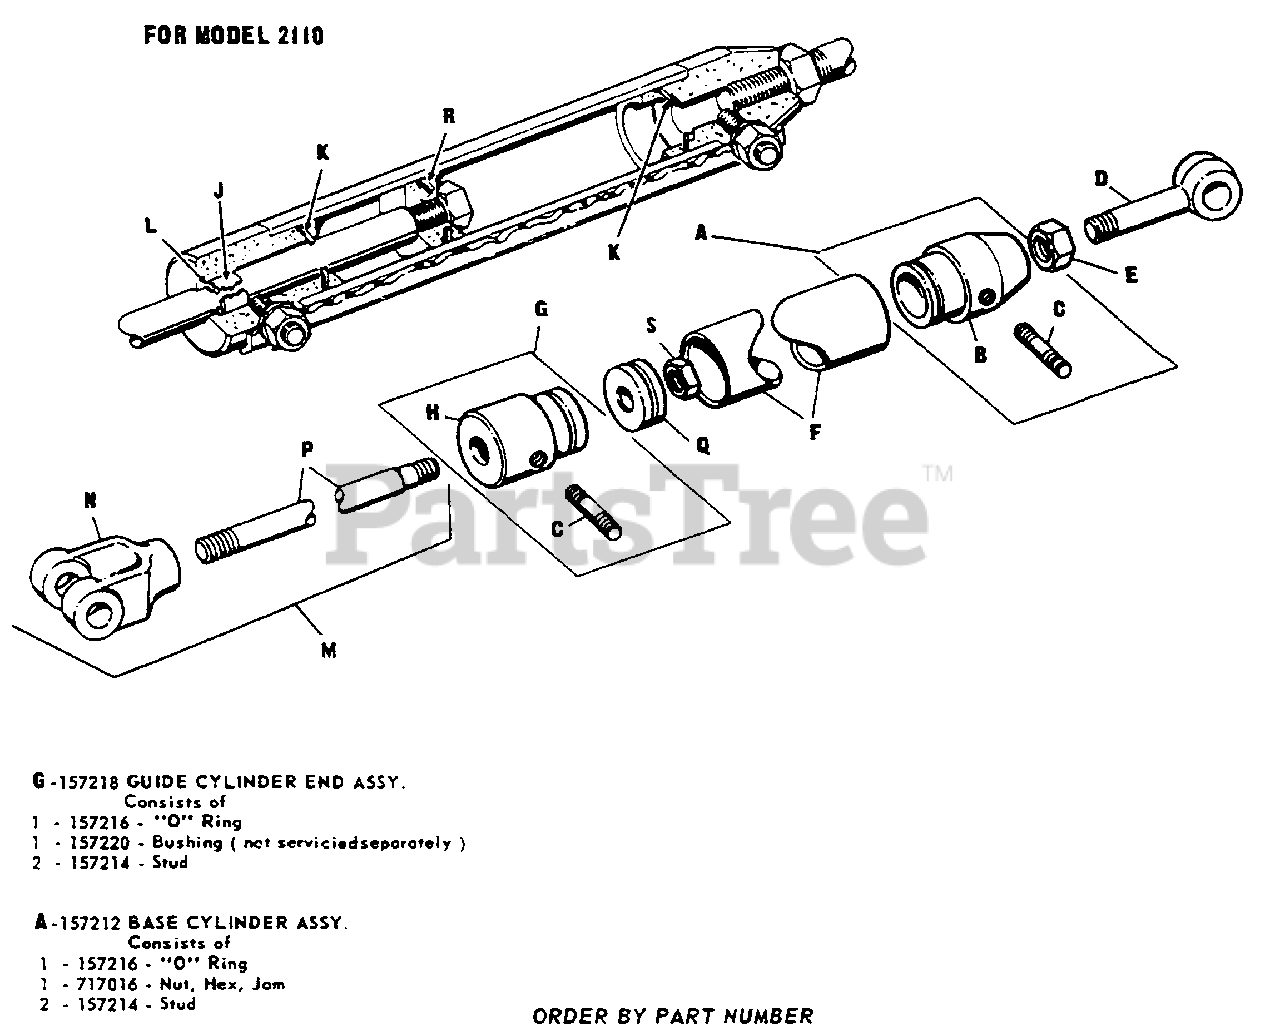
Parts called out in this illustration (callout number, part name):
A	Cylinder Base Sub-Assembly
B	Cylinder Base
C	Stud Bolt, 5/16"-18 x 7/8"
E	Jam Hex. Nut, 1/2"-20
G	Sub Assembly Guide
H	Cylinder End Guide
L	"O" Ring (157670 on 569)
M	Yoke & Rod Sub-Assembly
P	Piston Rod
R	"O" Ring (157668 on 569)
S	Full Hex. Nut
